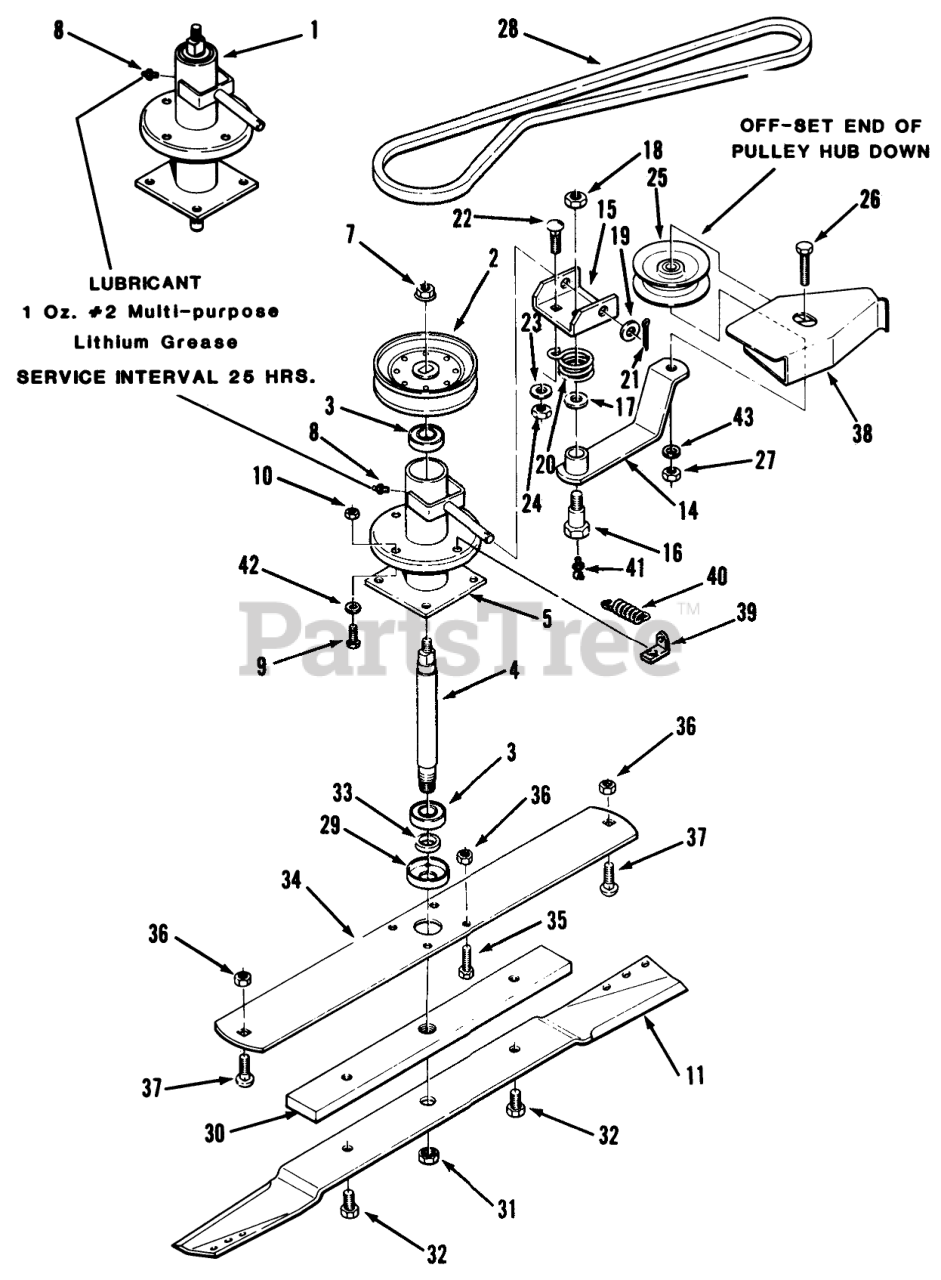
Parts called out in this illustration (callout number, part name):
1	Spindle Complete (includes items 3, 4, 5, 6 & 8).
2	PULLEY SPINDLE
3	BALL BEARING
4	SHAFT SPINDLE
5	ASS'Y-BLADE HOUSI R
7	NUT 3/8-24 WHIZLOCK
8	Zerk
9	Bolt
10	Nut
11	S/A-30' BLADE ASM
14	ASSY LEVER R
15	CHANNEL PIVOT R
16	SHOULDER BOLT
17	WASHER
18	NUT-JAM(7/16-14)
19	Washer
20	SPRING-TORSION
21	Cotter Pin
22	Bolt
23	Washer
24	NUT
25	PULLEY IDLER R
26	Bolt
27	NUT
28	Mower Drive Belt
29	CUP SPINDLE
30	BAR BLADE R
31	Jam Nut
32	HEX BOLT 1/2-13X3/4
33	SPACER-BLADE
34	PLATE SUPPORT R
35	BOLT
36	NUT
37	Carriage Bolt 3/8-16 X 3/4
38	COVER BELT R
39	CLIP - SPRING
40	SPRING-EXTENSION
41	ZERK 90DEGREE
42	Lockwasher
43	WASHER
